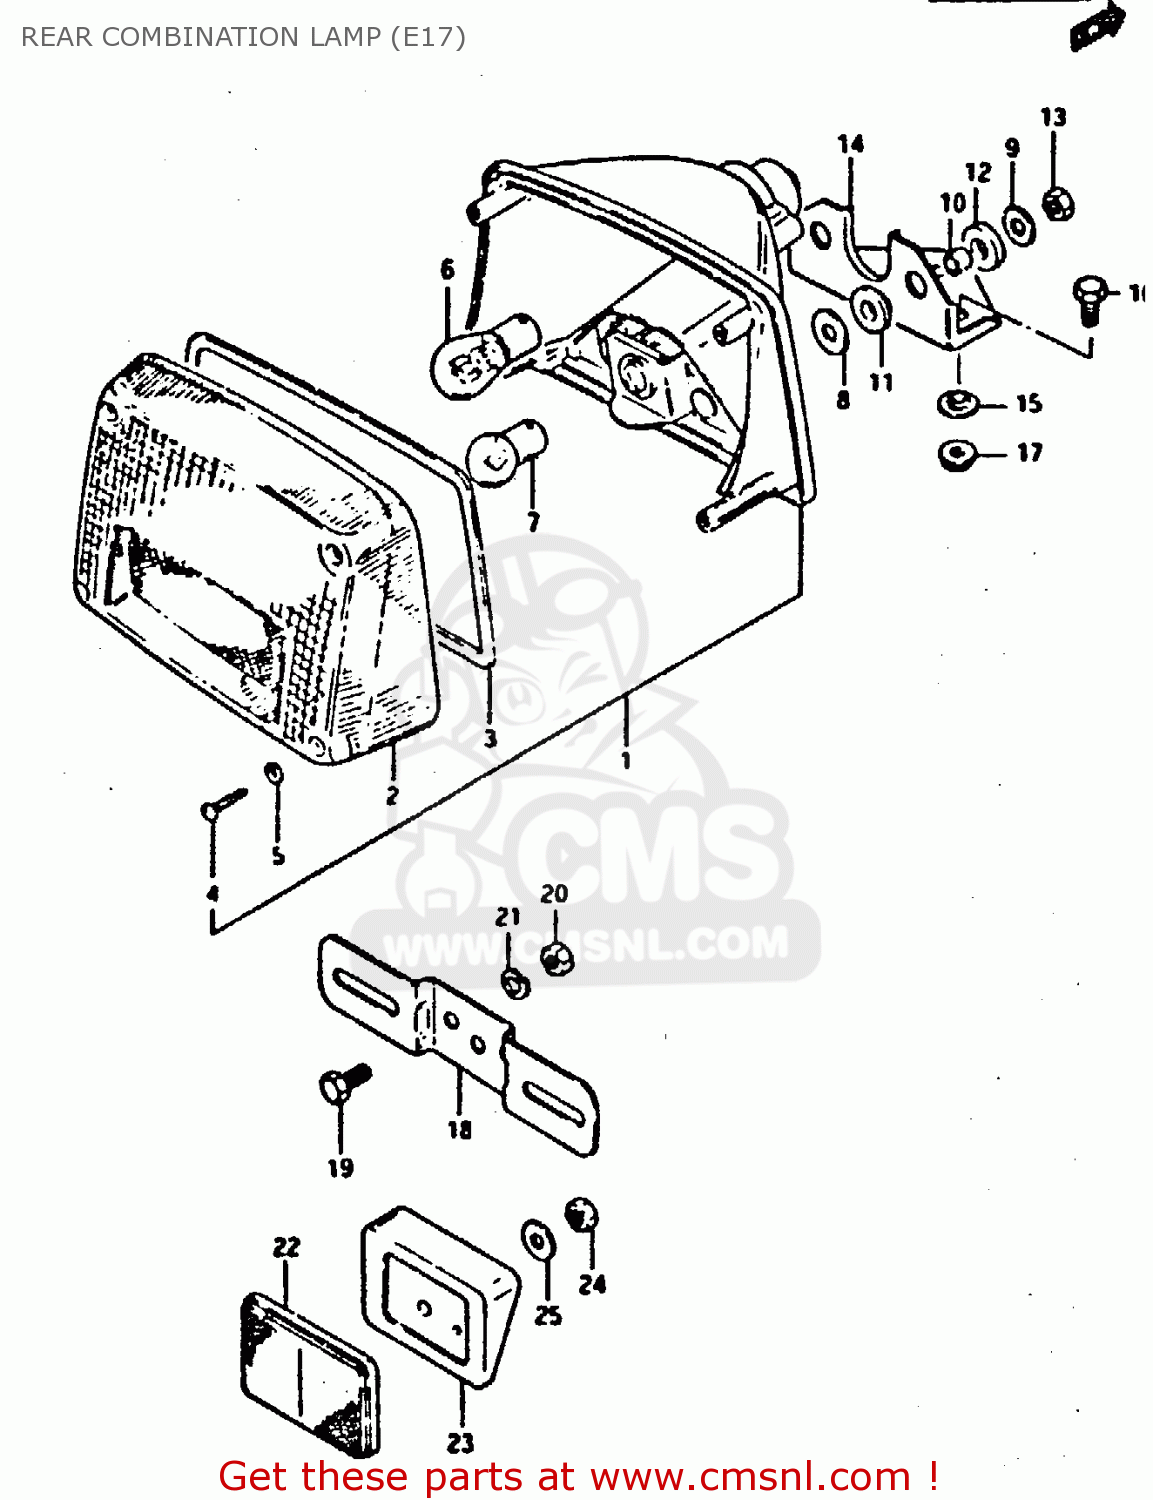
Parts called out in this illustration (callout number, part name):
1	LAMP ASSY, REAR COMBINATION
2	LENS
3	GASKET (NAS)
4	SCREW,REAR COMBINATION LAMP
5	GASKET (NAS)
6	BULB 12V21/5W
7	BULB
8	WASHER
9	WASHER
10	SPACER(6.1X9X7.5)
11	CUSHION
12	CUSHION
13	NUT 6MM
14	BRACKET,RR COMBINATION LAMP
15	WASHER
16	BOLT, UPPER
17	NUT 6MM
18	BRACKET, LICENSE PLATE
19	BOLT,REAR
20	NUT
21	LOCK WASHER
22	REFLEX REFLECTOR,RR
23	SPACER
24	NUT
25	WASHER(5.2X16X1)
